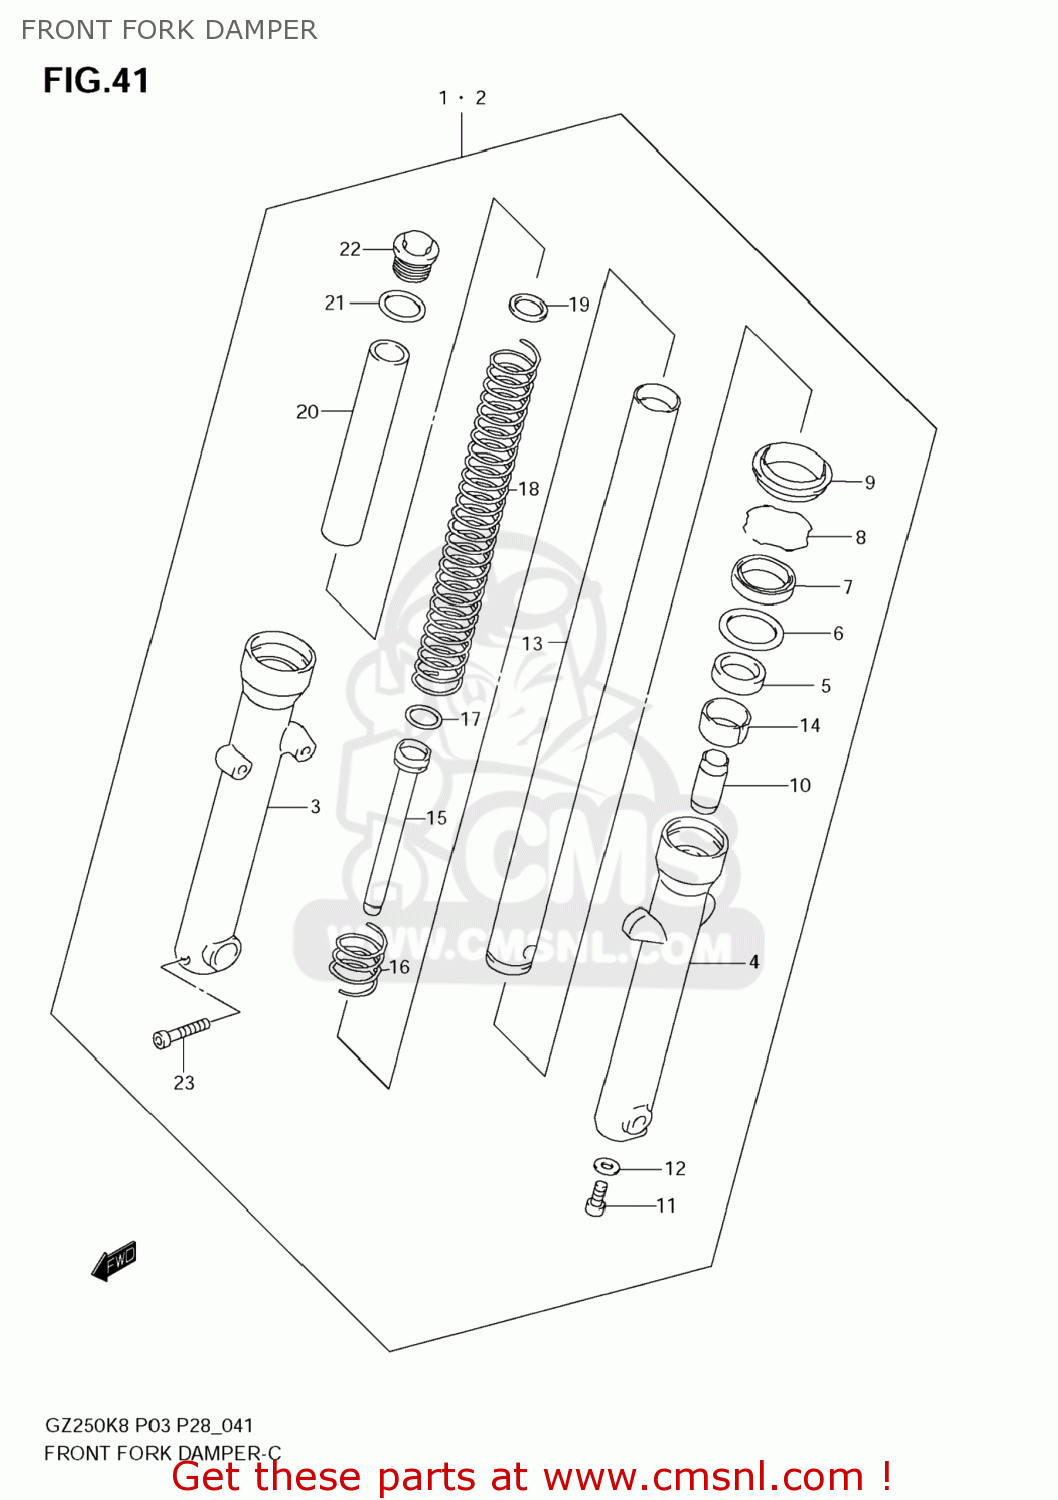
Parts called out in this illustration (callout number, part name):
1	DAMPER ASSY,FR FORK,R
2	DAMPER ASSY GZ
3	TUBE OUTER R
4	TUBE, OUTER LH
6	SPACER, SEAL
7	SEAL, OIL
8	RING, STOPPER
9	SEAL, DUST
10	PIECE, OIL LOCK
11	BOLT
12	GASKET (NAS)
13	INNER TUBE
14	BUSH,SLIDE
15	PIPE,SEAT
16	SPRING,REBOUND
17	RING,PISTON
18	SPRING,FR
19	JOINT,SPRING
20	COLLAR, SPRING
21	O RING
22	BOLT,FR FORK
23	BOLT
